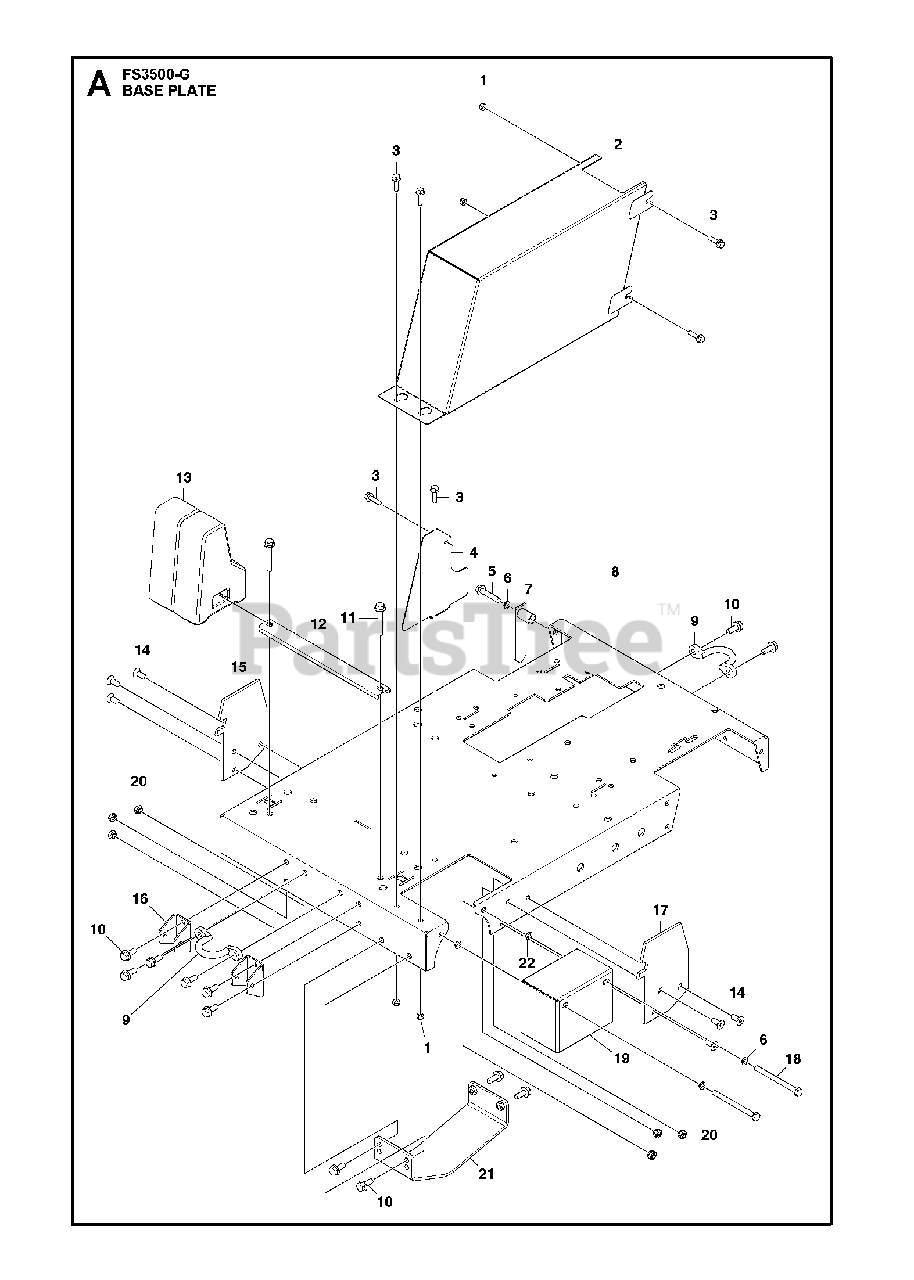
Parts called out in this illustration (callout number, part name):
1	HEXAGON LOCKING NUT
20	HEXAGON LOCKING NUT
21	BELT GUARD"26""-30"""
